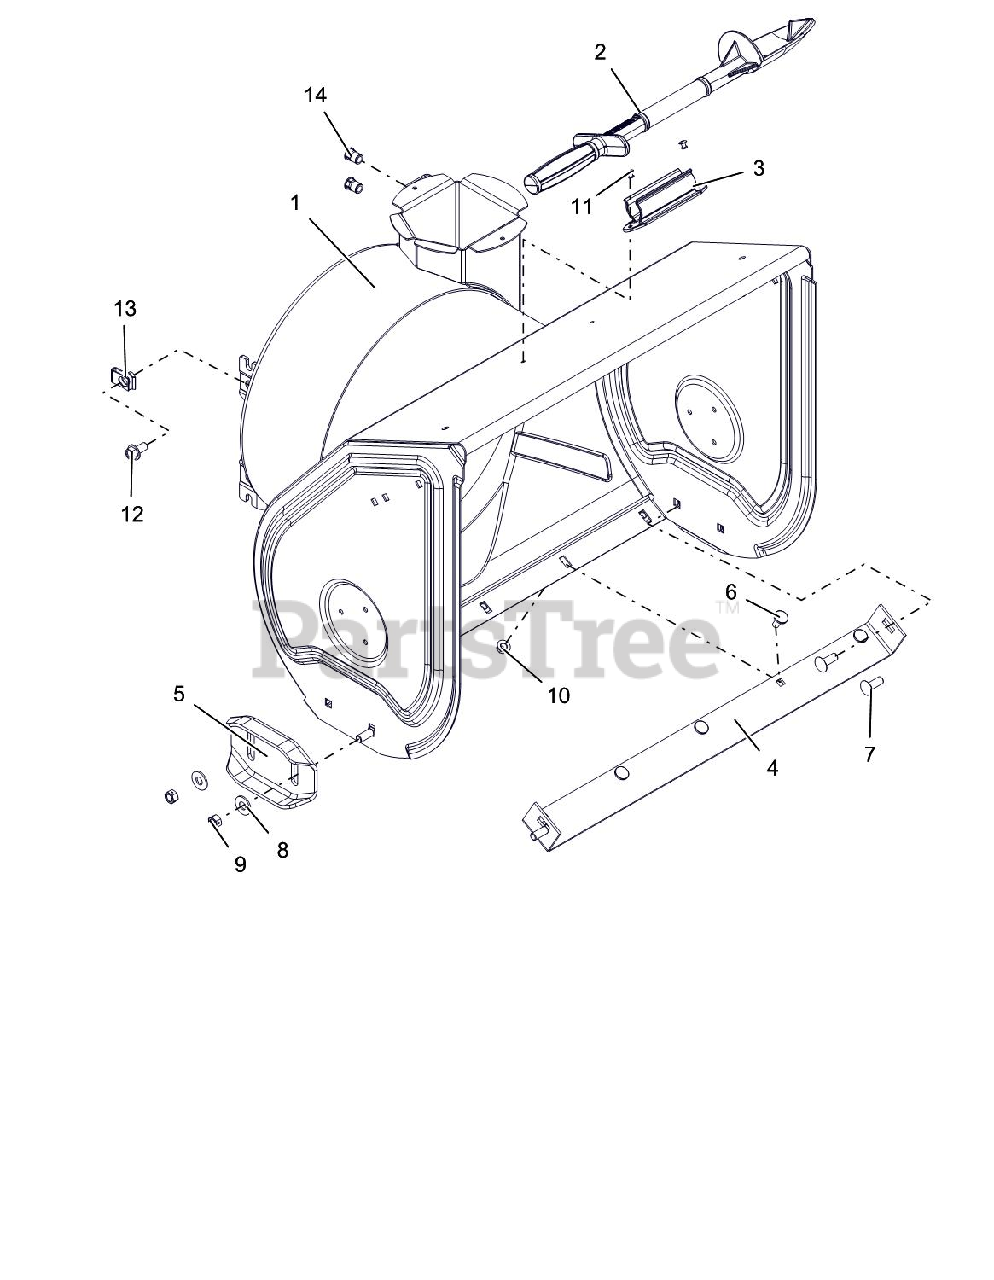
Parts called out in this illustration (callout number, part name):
1	BLOWER HOUSING W/DECAL 24"
2	DEVICE, SNOW CLEAN OUT
3	MOUNT, SNOW CLEAN OUT
4	BLADE, SCRAPER-24"
5	SKID SHOE, REVERSIBLE - ORANGE
6	BOLT, MODIFIED HEAD CARRIAGE
7	@BLT-RDHDSHSQNK.38-16X1.0 G5YZ
8	@WSHR-FL-STL.438X1.00X.083 YWZ
9	@NUT-LK-CTR .38-16 YWZC
10	@NUT-LK-TOP-FLG .31-18 YWZC
11	RVT-POP .187 YZ
12	BLT-SERHFWH .38-16X.75 YWZC
13	NUT-RTNR .375-16X.37
14	NUT, THREADED INSERT .38-16
